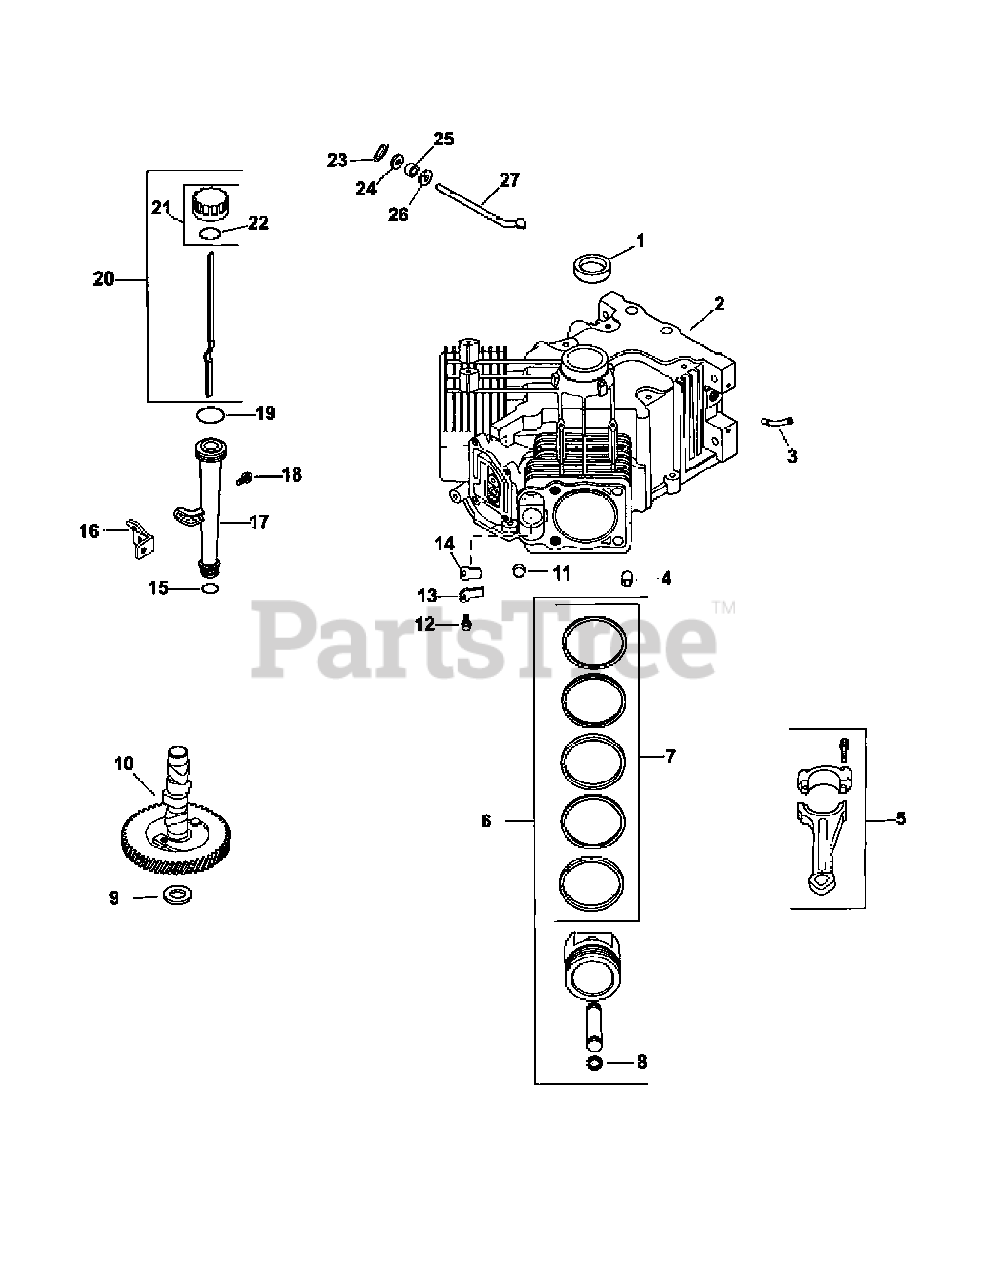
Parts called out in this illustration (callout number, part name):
1	Seal, Front Oil
2	Crankcase
5	Connecting Rod (Std.)
5	Connecting Rod (.025)
6	Piston w/Ring Set (Std.)
6	Piston w/Ring Set (.080)
6	Piston w/Ring Set (.25)
6	Piston w/Ring Set (.50)
7	Ring Set (Std. & .080)
7	Ring Set (.25)
7	Ring Set (.50)
8	Piston Pin Retainer
9	Camshaft Shim-Red
9	Camshaft Shim-Black
9	Camshaft Shim-White
9	Camshaft Shim-Blue
9	Camshaft Shim-Yellow
9	Camshaft Shim-Green
9	Camshaft Shim-Gray
10	Camshaft
12	Hex Flange Screw M5 x .8 x 10
13	Reed Retainer
14	Breather Reed
16	Bracket
17	Oil Fill Tube
18	Hex Flange Screw M5 x .8 x 16
20	Dipstick Assembly
21	Oil Fill Cap Kit
22	Dipstick O-Ring
23	Retainer Ring
24	Plain Washer 9mm
25	Governor Cross Shaft Seal
26	Plain Washer 1/4"
27	Governor Cross Shaft
